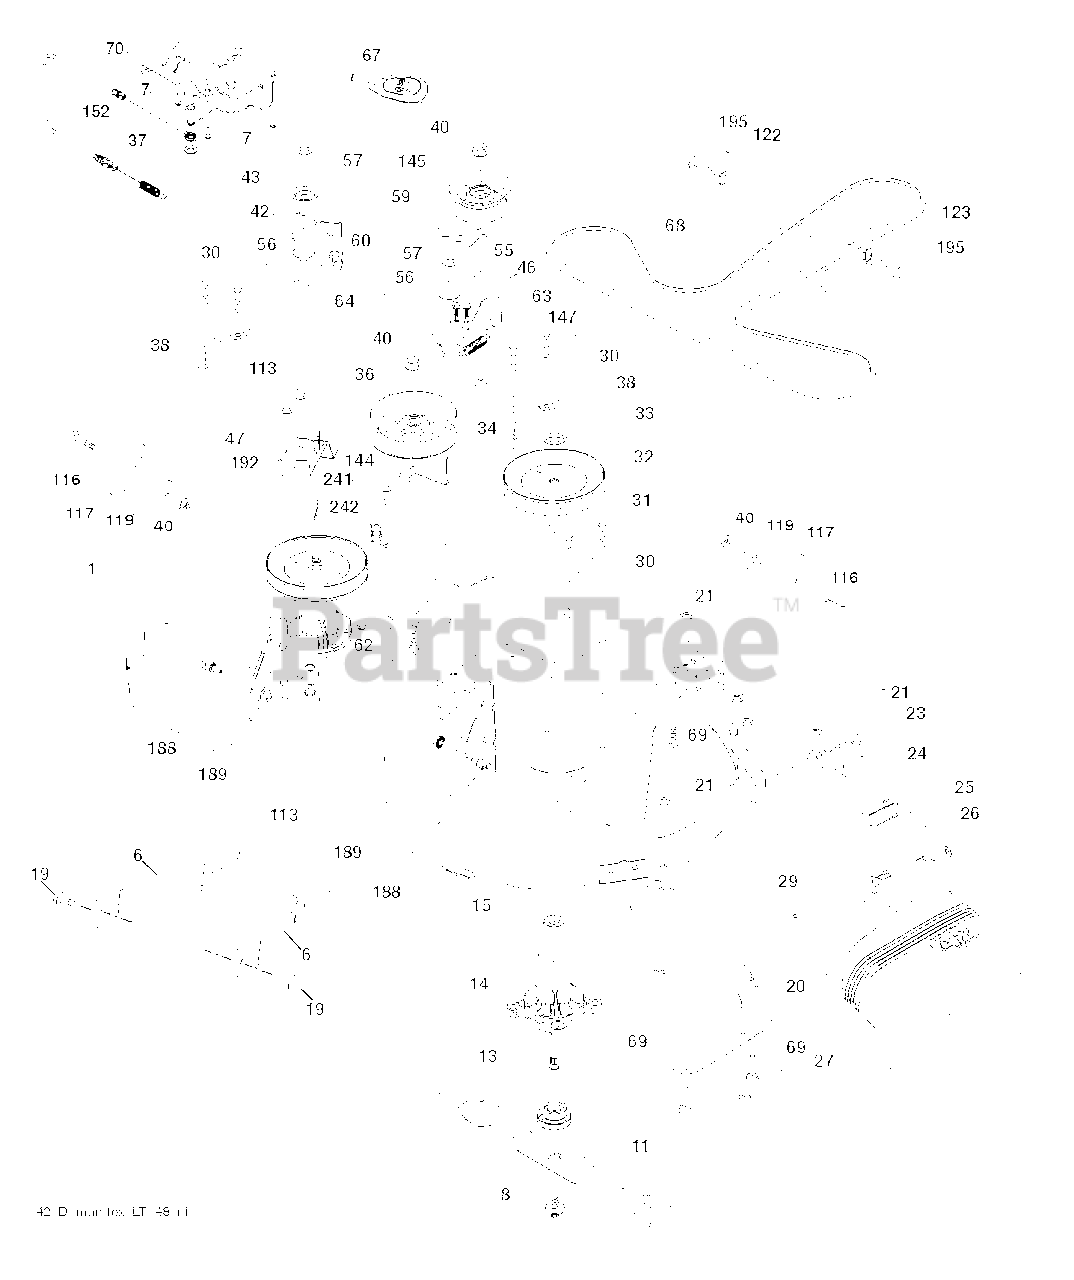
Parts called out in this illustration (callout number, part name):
6	ARM.SUSPENSION.MOWER.R
7	SCREW.#10 X 0.750.BOS THREAD
8	BOLT.WASHER.ASM.7/16-2
11	42" HI-LIFT BLADE
13	SHAFT.ASM.MDRL.N/GREASE.38
14	HOUSING MANDREL
15	BEARING
19	BOLT.SHOULDER
23	BRKT.DEFLECTOR.38"2005+
24	CAP-SLEEVE LT
25	SPRING.TORSION.DEFLECT
26	NUT PUSH M
29	ROD.HINGE
30	SCREW, WASHER HEAD
31	WASHER.SPACER.MANDREL
33	NUT.FLANGE.LOCK.TOP
34	BOLT.3/8-16X1.50
37	WASHER
46	SCREW.1/4-20X5/8
55	IDLER.ARM.42"
56	SPACER.RETAINER
57	SCREW 3/8-16X1
59	GUARD, BELT
69	BOLT
117	WHEEL.GAGE.HALF.SPOKED
188	STUD.FASTNER.W/ANTI-ROTATE
189	NUT LOCK HEX FLANGE 5/16-18
195	SCREW, 3/8-16X3/4
242	PORT.WASHOUT
